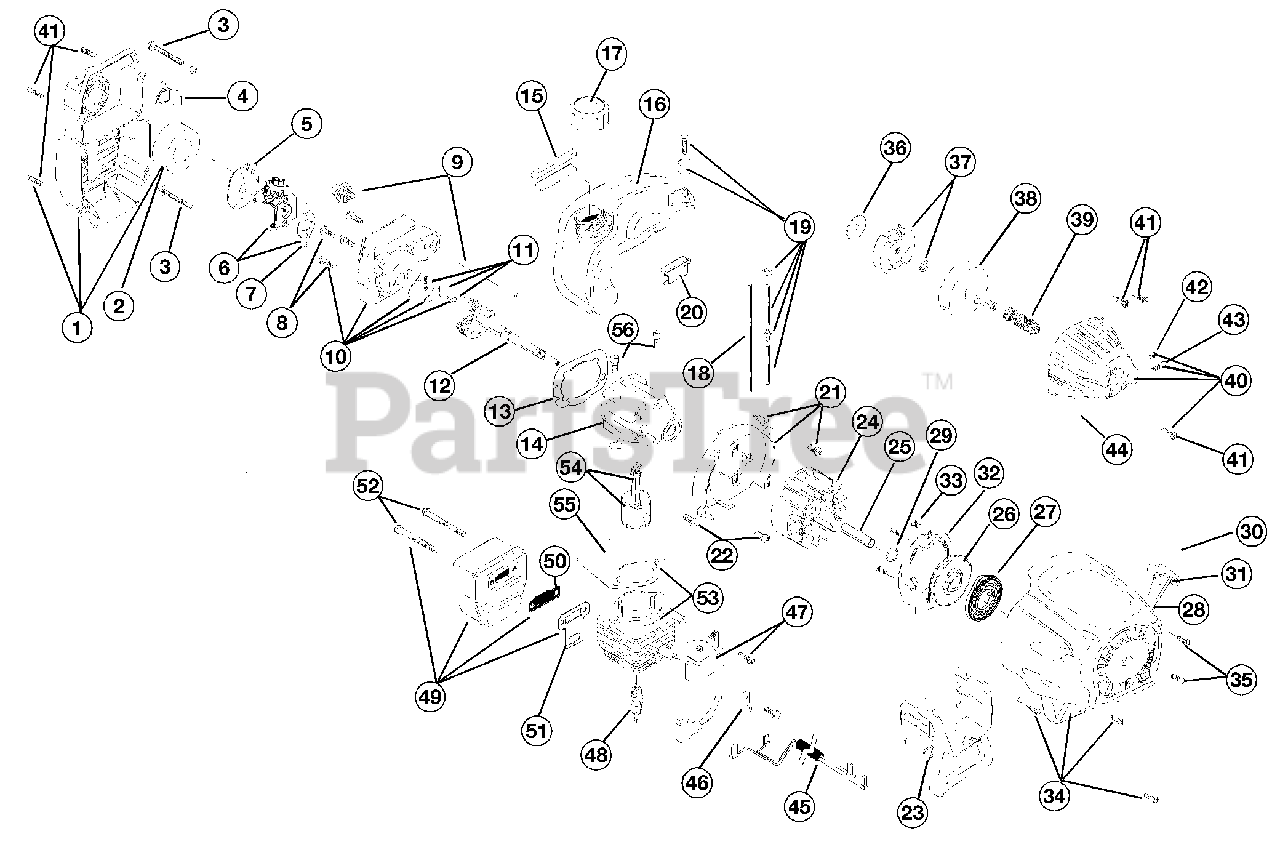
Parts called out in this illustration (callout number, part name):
1	Air Cleaner/Muffler Cover Assembly
2	Air Cleaner Filter
3	Carburetor Mounting Screw Assembly
4	Choke Extension
5	Choke Plate
6	Carburetor Assembly W/Limiter Caps
7	Carburetor Gasket
8	Carb Mount Screw
9	Primer and Hose Assembly
10	Carb Mount Assembly
11	Reed Assembly
12	Power Shaft Assembly
13	Carburetor Mount Gasket
14	Crank Case Service Assembly
15	Rear Mounting Pad
16	Fuel Tank Assembly
17	Fuel Cap Assembly
18	Fuel Return Line
19	Fuel Line Assembly
20	Front Mounting Pad
21	Shroud Assembly
22	Shroud Screw
23	Shroud Extension and Stand
24	Flywheel Assembly
26	Recoil Pulley Assembly
27	Recoil Spring
28	Rope Guide
29	Pulley Retainer
30	Pull Handle
32	Pressure Plate Assembly
33	Plate Screw
34	Starter Housing Assembly
35	Housing Screw
36	Clutch Washer
37	Clutch Rotor Assembly
38	Clutch Drum Assembly
40	Clutch Cover Assembly
41	Cover Screw
42	Anti-Rotation Screw
43	Clamping Screw
44	Clamping Nut
45	Wire Leads and Sleeve
46	Ground Tab
47	Module Assembly
49	Muffler Assembly
50	Spark Arrestor Screen
51	Exhaust Gasket
52	Muffler Mounting Bolt Assembly
53	Cylinder Assembly
54	Piston and Rod Assembly
55	Cylinder Gasket
56	Cylinder Bolt
